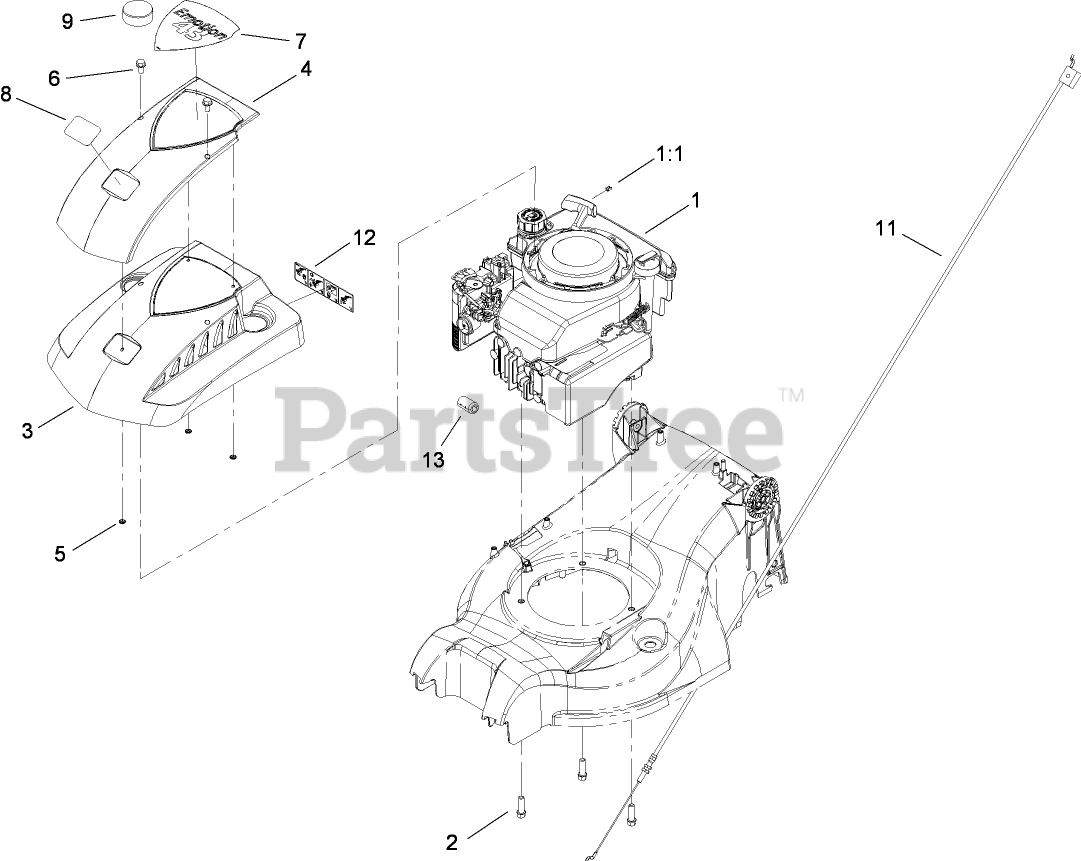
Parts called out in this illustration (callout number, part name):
1	Loose Parts Package
1:1	STOP-ROPE
2	SCREW-TAPTITE
3	SHROUD-ENGINE
4	COVER-SHROUD, ENGINE
5	CLIP-PUSH
6	SCREW-HWHTF
9	CAP-GAS
13	FERRITE-SNAP ON
